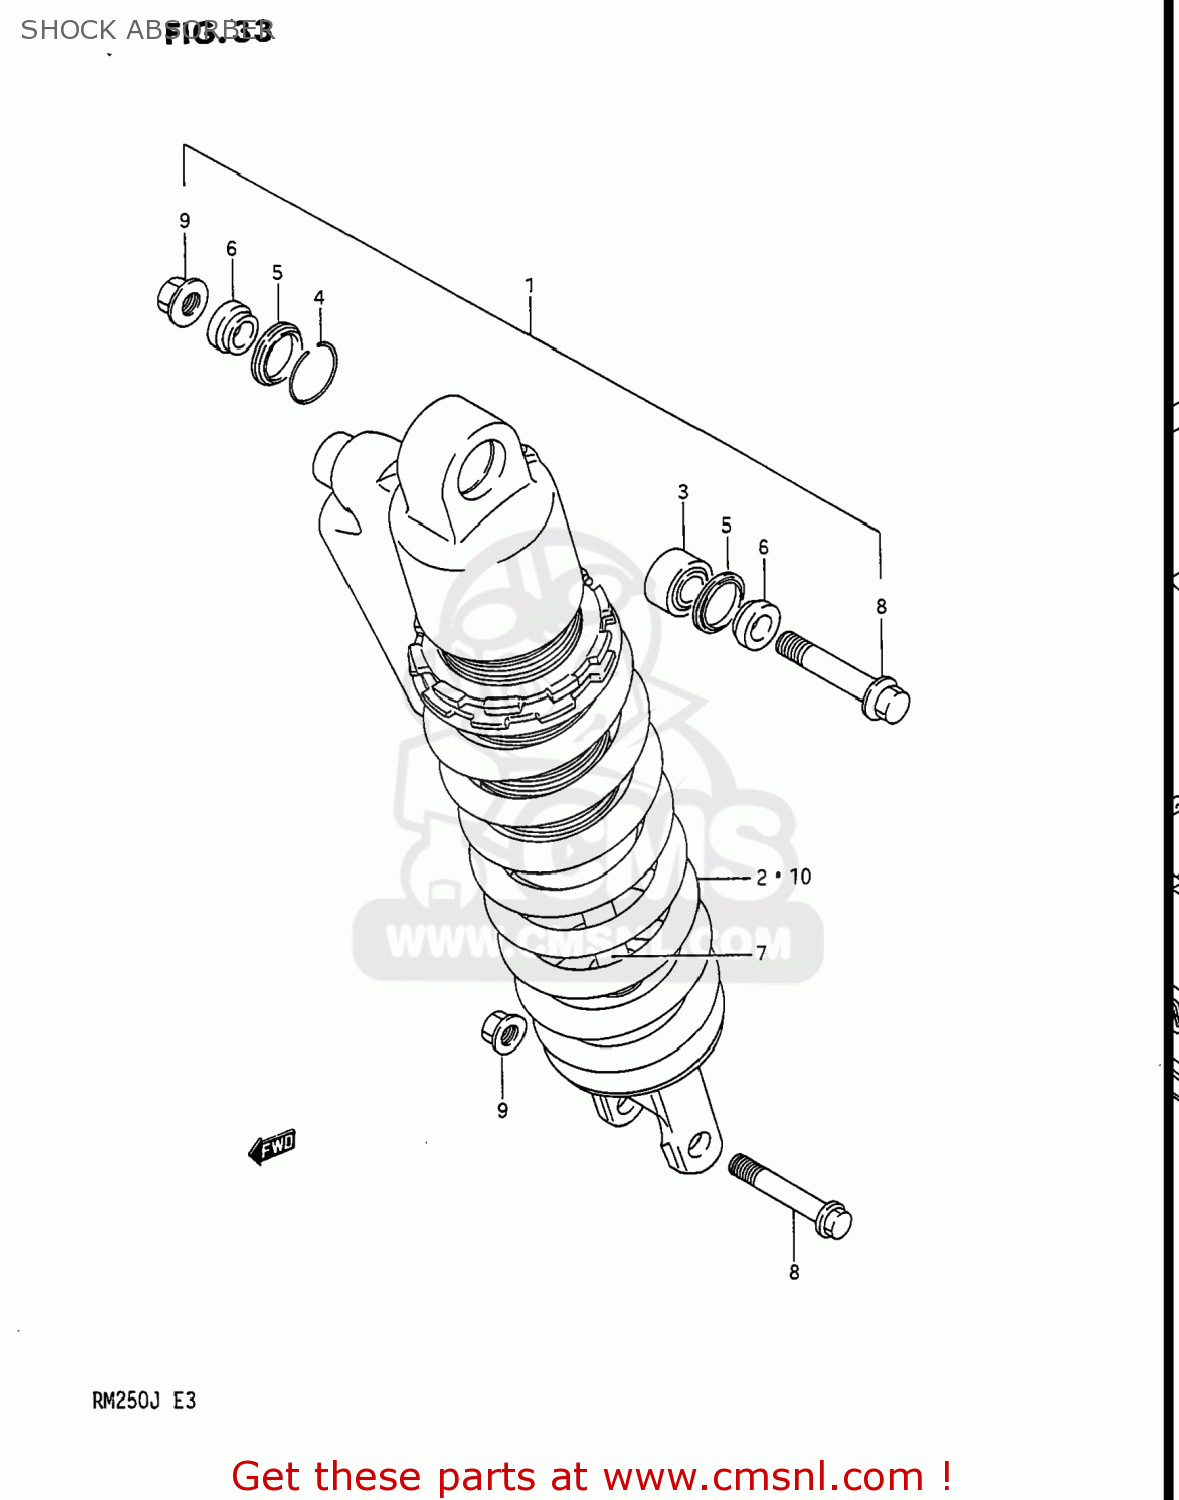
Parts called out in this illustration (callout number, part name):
1	ABSORBER ASSEMBLY,REAR SHOCK
2	SPRING
3	BEARING,RR CUSHION LEVER
4	RING
5	DUST SEAL
6	SPACER
7	ROD,PISTON
8	BOLT,REAR SHOCK ABSORBER
9	NUT
10	SPRING
